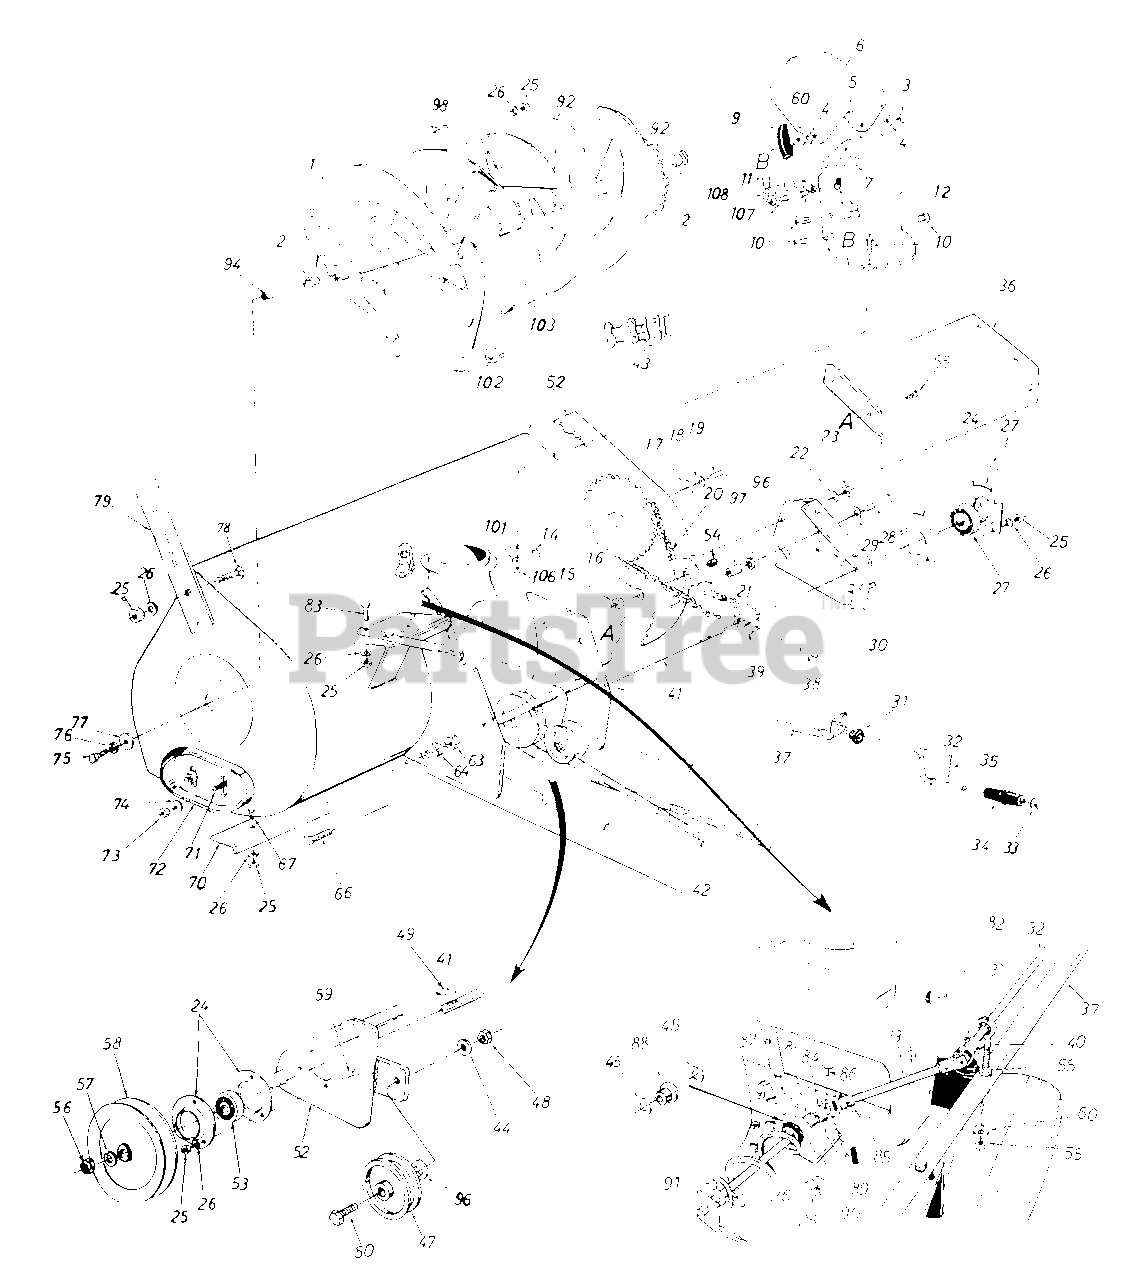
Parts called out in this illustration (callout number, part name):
3	Hex Cent. L.-Nut 5/16-18 Thd.
4	Fl.-Wash. .344" I.D.
5	Truss Mach. Scr. 5/16-18 x .75" Lg.
6	Upper Chute
7	Carriage Bolt 5/16-18 x 1.0" Lg.*
8	Hex L-Nut 1/4-20 Thd.
9	Hand Knob
10	Truss Mach. Scr. 1/4-20 x .75" Lg.
11	Ext Spring
12	Lower Chute
13	Chute Crank Extension Rod
14	Chute Flange Keeper
15	L.-Nut 3/8-16 Thd.
16	Fl.-Wash.
17	Fl.-Wash.
18	Belleville Wash.
19	Hex Bolt 1/2-13 x 1.00" Lg.*
20	#420 Chain 1/2" Pitch x 77 Links
21	Plastic Idler 2.00" O.D.
22	L.-Wash. 114" I.D.*
23	Hex Nut 1/4-20 Thd.*
24	Bearing Housing
25	Hex Nut 5/16-18 Thd.*
26	L.-Wash. 5/16" I.D.*
27	Self-Aligning Bearing
28	Hex Bolt 3/8-16 x 1.75" Lg.*
29	Belleville Wash. 3/8" I.D.
32	Chute Crank .375 Dia. x 34.5" Lg.
33	Push Nut 3/8" Rod
34	Knob (Black)
35	Roll Pin
39	14 Teeth Sprocket Ass'y.
40	Eyebolt 5/16-18 x 3.0" Lg.
41	Drive Shaft
42	"V" Belt
43	Master Link for #420 Chain
44	L.-Wash. 3/8" I.D.*
45	Fl.-Wash. .385 I.D. x .62" O.D.
47	Fl.-Idler with Flanges
48	Hex Jam L.-Nut 3/8-16 Thd.
49	#61 Hi-Pro Key 3/16 x 518" Dia.
50	Hex Bolt 3/8-16 x 1.75" Lg.*
52	Spiral Housing Ass'y.
53	Self-Aligning Bearing
54	Sleeve Bearing .50" I.D.
55	Hex Nut 5/16-18 Thd.*
56	Hex Nut 3/4-10 Thd.
57	L.-Wash. 3/4" I.D.
58	"V"Pulley .750" I.D. x 6.00"O.D.
59	Hex Sems Bolt 5/16-18 x .75" Lg .*
60	Bell-Wash. .345" I.D. x .88" O.D.
63	Hex Nut 1/2-13 Thd.*
64	L.-Wash. 1/2" I.D.*
65	Hex Wash. Hd. Tap Scr. 1/4-20 x .50" Lg.
66	Hex Bolt 1/2-13 x 2.75" Lg.*
67	Carriage Bolt 5/16-18 x .75"*
72	Skid Shoe
73	Hex Jam Nut 3/8-16 Thd.
74	Belleville Wash. 3/8" I.D.
75	Hex Bolt 1/2-13 x 1.00" Lg.*
76	Belleville Wash. 1/2" I.D.
77	Fl.-Wash.
78	Carriage Bolt 5/16-18 x .62" Lg.*
82	Cotter Pin
83	Hex Bolt 5/16-18 x 1.50" Lg.*
84	Joint Block
85	Joint Bracket Ass'y.
86	Oval Head Rivet
87	Spring Pin Roll 1/8" Dia. x .75" Lg.*
88	Nylon Bushing
89	Carriage Bolt 5/16-18 x .75" Lg.
90	Chute Crank Bracket
91	Chute Crank Ass'y.
96	Flat Washer
97	Idler Spacer
98	Carriage Bolt 5/16-18 x .75" Lg.
101	Fl.-Wash. 1/4" I.D.
102	Plastic Bushing
107	Shld. Nut 1/4-20 Thd.
05139A-0637	BLADE-GUIDE (DRIFT - POWDER BLACK (0637)
05139A-0638	BLADE-GUIDE (DRIFT - MTD/TROY-BILT RED (0638)
05139A-0662	BLADE-GUIDE (DRIFT - OYSTER GRAY (0662)
05139A-0665	BLADE-GUIDE (DRIFT - YARDMAN GREEN (0665)
05139A-0674	BLADE-GUIDE (DRIFT - YARDMAN YELLOW (0674)
05139A-0716	BLADE-GUIDE (DRIFT - CUB YELLOW-99 (0716)
